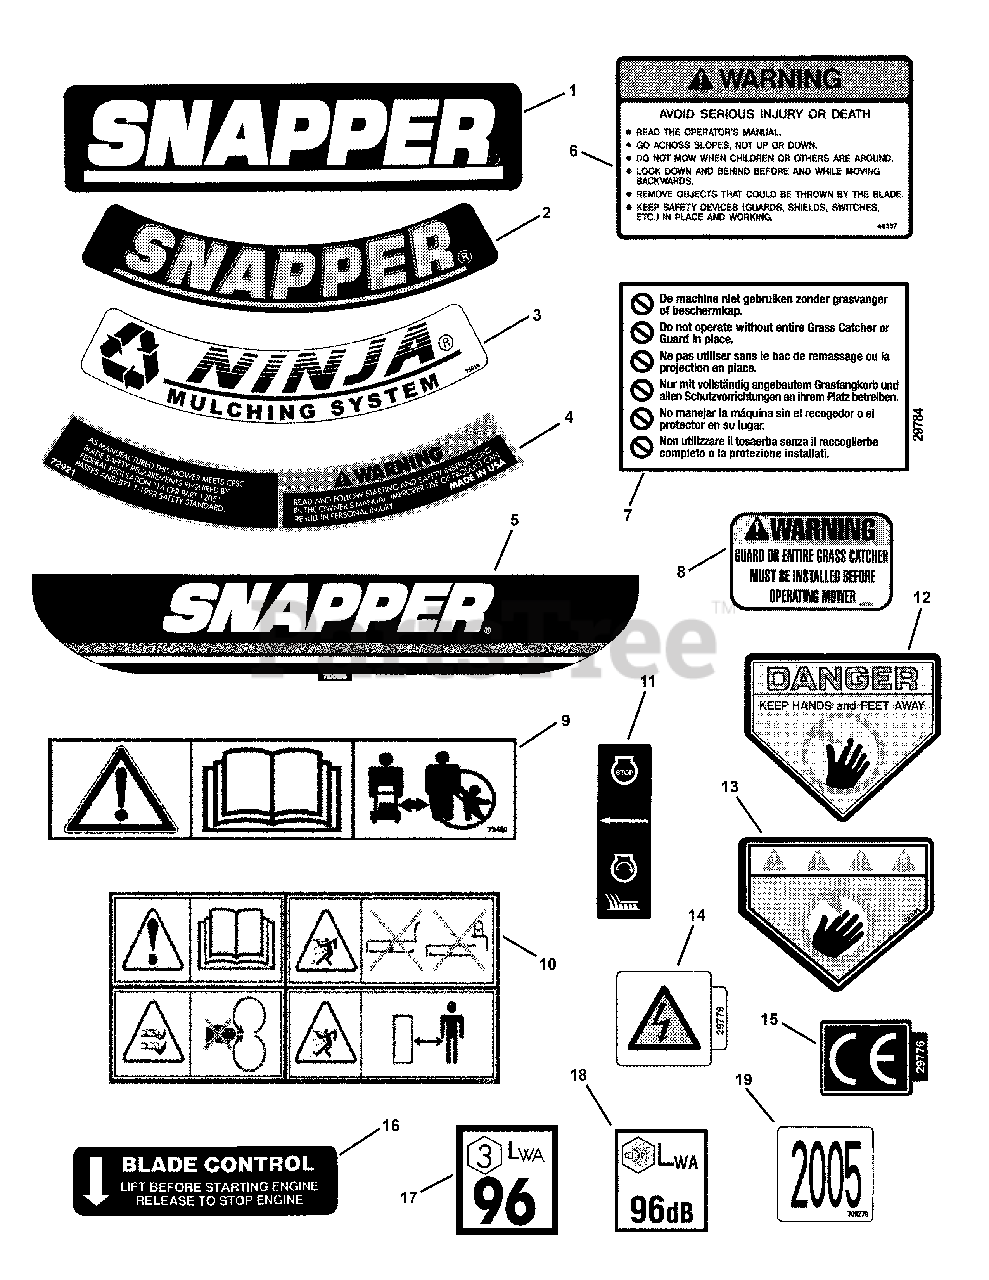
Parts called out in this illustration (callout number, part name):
1	DECAL, SNAPPER
2	DECAL, SNAPPER
3	DECAL, Ninja
4	DECAL, Feature/Compliance
5	DECAL, SNAPPER, Steel Decks
6	DECAL, Warning 1997
7	DECAL, Deck/Chute International Warning
8	DECAL, Chute/Opening
9	DECAL, Caution Symbols
10	DECAL, Warning, Euro Multi-Panel
11	DECAL, OPC (International Symbol)
12	DECAL, Danger (Keep Hands and Feet Away)
13	DECAL, Warning (International Symbol)
14	DECAL, Spark Plug (International Symbol)
15	DECAL, European Community (CE)
16	DECAL, Blade Control
17	DECAL, Noise Control
18	DECAL, Sound 96
19	DECAL, 2005 Year of Manufacture
